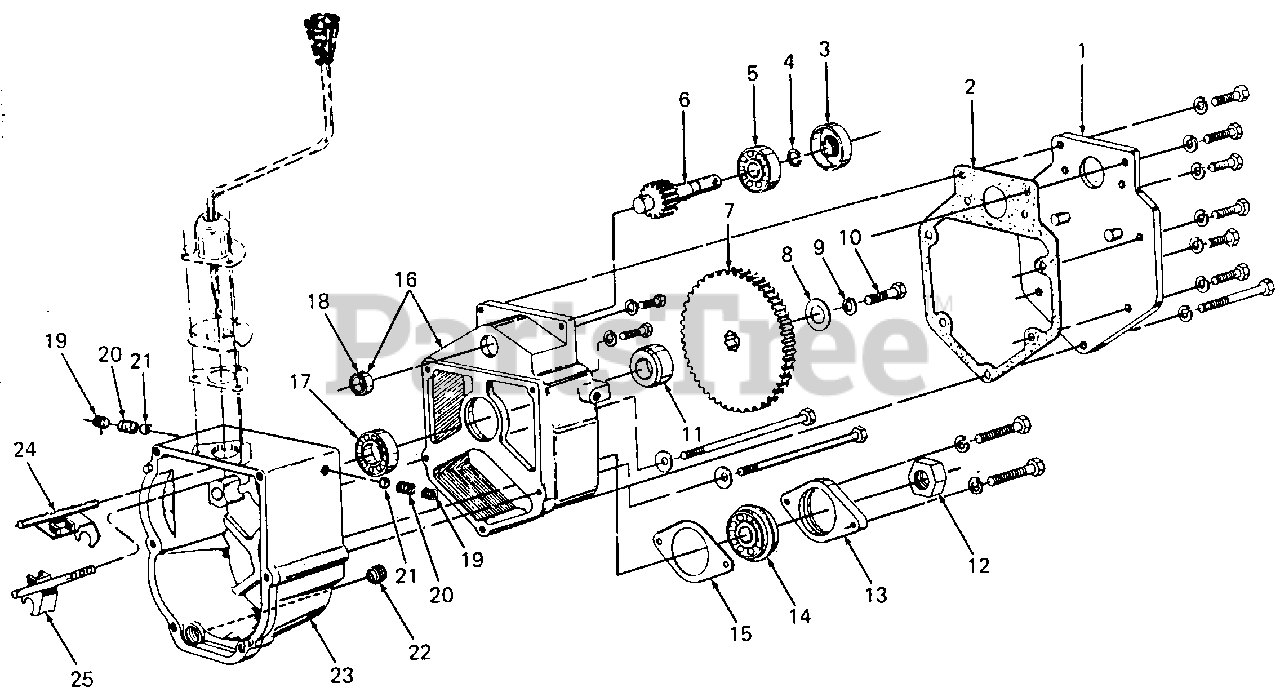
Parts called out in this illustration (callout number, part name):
1	Plate, Front Cover
2	Gasket, Front Cover
3	Seal, Oil, 5/8 ID X 1.574 OD X .312 Wide
4	Ring, Retaining
5	Bearing, Ball
6	Shaft, Input
7	Gear, Reduction - 84T
8	Washer, Flat, 1/2 ID X 1-1/2 OD X 3/16 Thk
9	Washer, Lock, 7/16
10	Screw, Hex Cap, 7/16-14 X 1.0 Lg GR5
11	Spacer, Gear
12	Nut, Hex Jam, 3/4-16 GR5
13	Retainer, Bearing
14	Bearing, Ball w/Ring
15	Shim, Bearing Retainer, .004
16	Housing, Reduction Drive
17	Bearing, Ball
18	Bearing, Needle
19	Screw, Set, 1/2-20 X 7/16 Lg
20	Spring, Detent
21	Ball, Detent, 3/8 Dia
22	Plug, Drain
23	Housing, Gear
24	Fork, Shift - LH
25	Fork, Shift - RH
